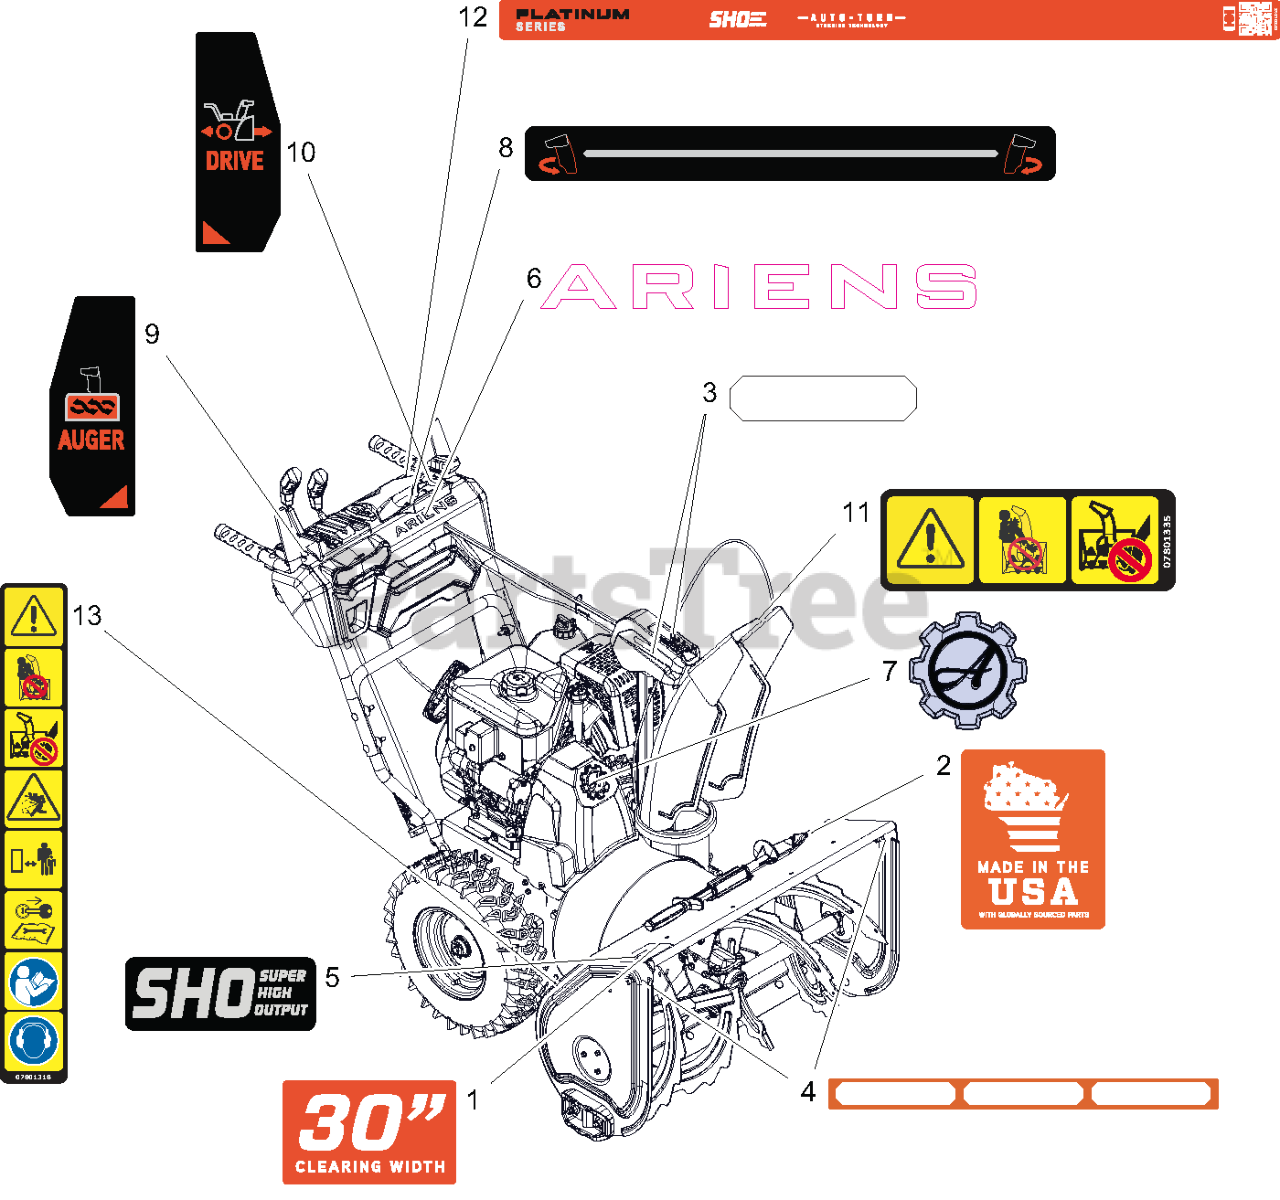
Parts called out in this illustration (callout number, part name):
1	DECAL- CLEARING - 30
2	DECAL- MADE IN USA
3	DECAL,REFLECTIVE,GEAR COVER
4	DECAL,REFLECTIVE,HOUSING
5	DECAL, SHO
6	DECAL- ARIENS - 7.46"
7	DECAL, ARIENS - GEAR BADGE
8	DECAL- CHUTE ROTATION
9	DECAL- CONTROL - AUGER
10	DECAL- CONTROL - DRIVE WHEEL
11	DECAL- DANGER
12	DECAL- DASH - PLT
13	DECAL- SAFETY - DANGER
